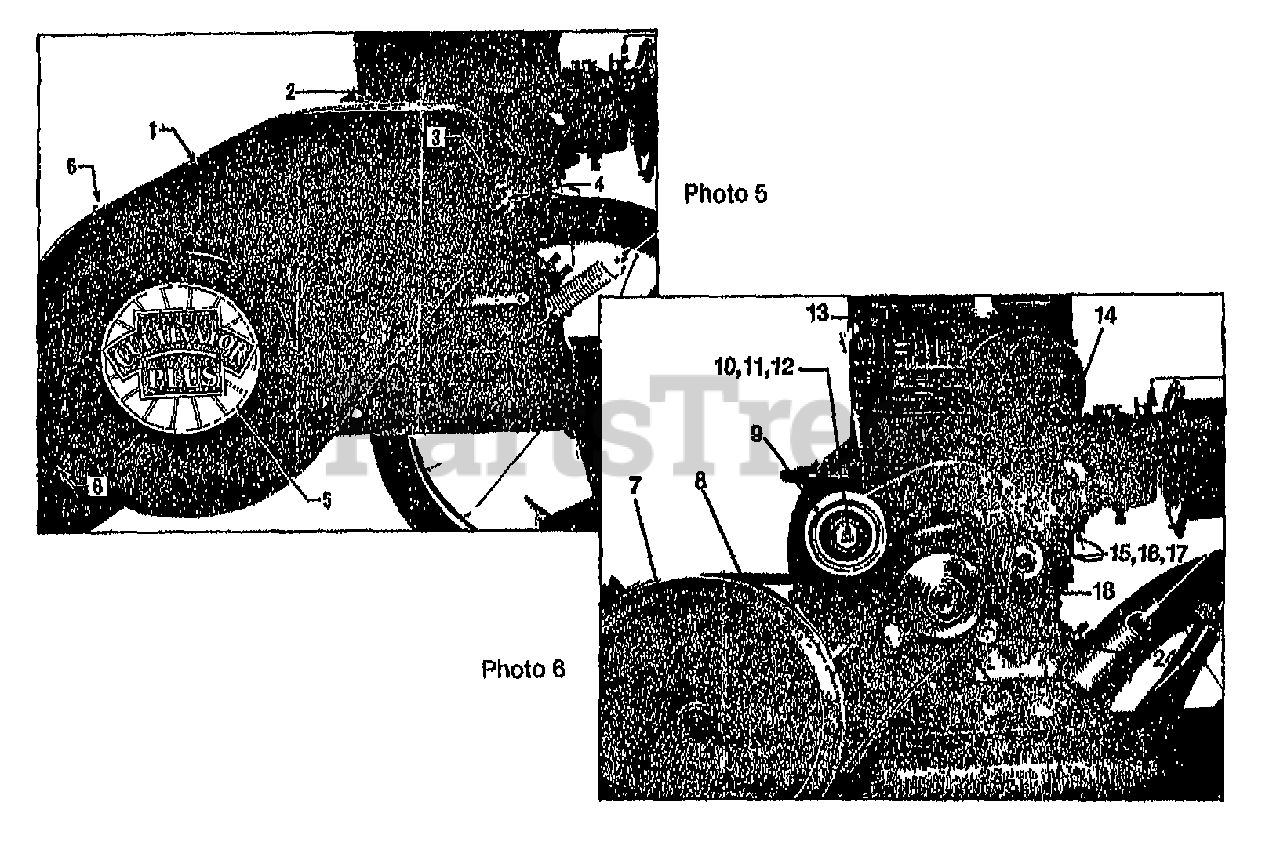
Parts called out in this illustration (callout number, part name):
1	COVER-BELT W/DECAL (INCL. 60028,9368, 60071, 60074)
2	DECAL-BELT GUARD WARN 60074
3	CUSHION
4	PIN-HITCH ZP
5	DECAL-"CULTIVATOR-PLUS"
6	SCR-HW M10-24X.375 ZP (ATTACHES BELT COVER TO PIVOT BRACKET)
7	PULLEY-DRIVEN PNT
8	BELT-V CULTIVATOR
9	PULLEY-IDLER ZP
10	BOLT-HH 3/8-16X1.5 FTH ZP (ATTACHES IDLER PULLEY TO SHAFT)
11	BUSHING-.5X.38X.4 (LOCATED BEHIND IDLER PULLEY)
12	NUT-H/LK 3/8-16 (LOCATED BEHIND IDLER PULLEY)
13	ASSM-IDLER ARM
14	BRKT-LOCKING PNT
15	SCR-HH 5/16-18X.5 GD5 YEL (ATTACHES IDLER ARM LOCKING BRACKET TO ENGINE)
16	WASHER-LK .312 ZP
17	WASHER-#1.125X.344 ZP
18	ASSM-IDLER PLATE
24	SCR-HH 5/16-24X.75 G5 ZP
